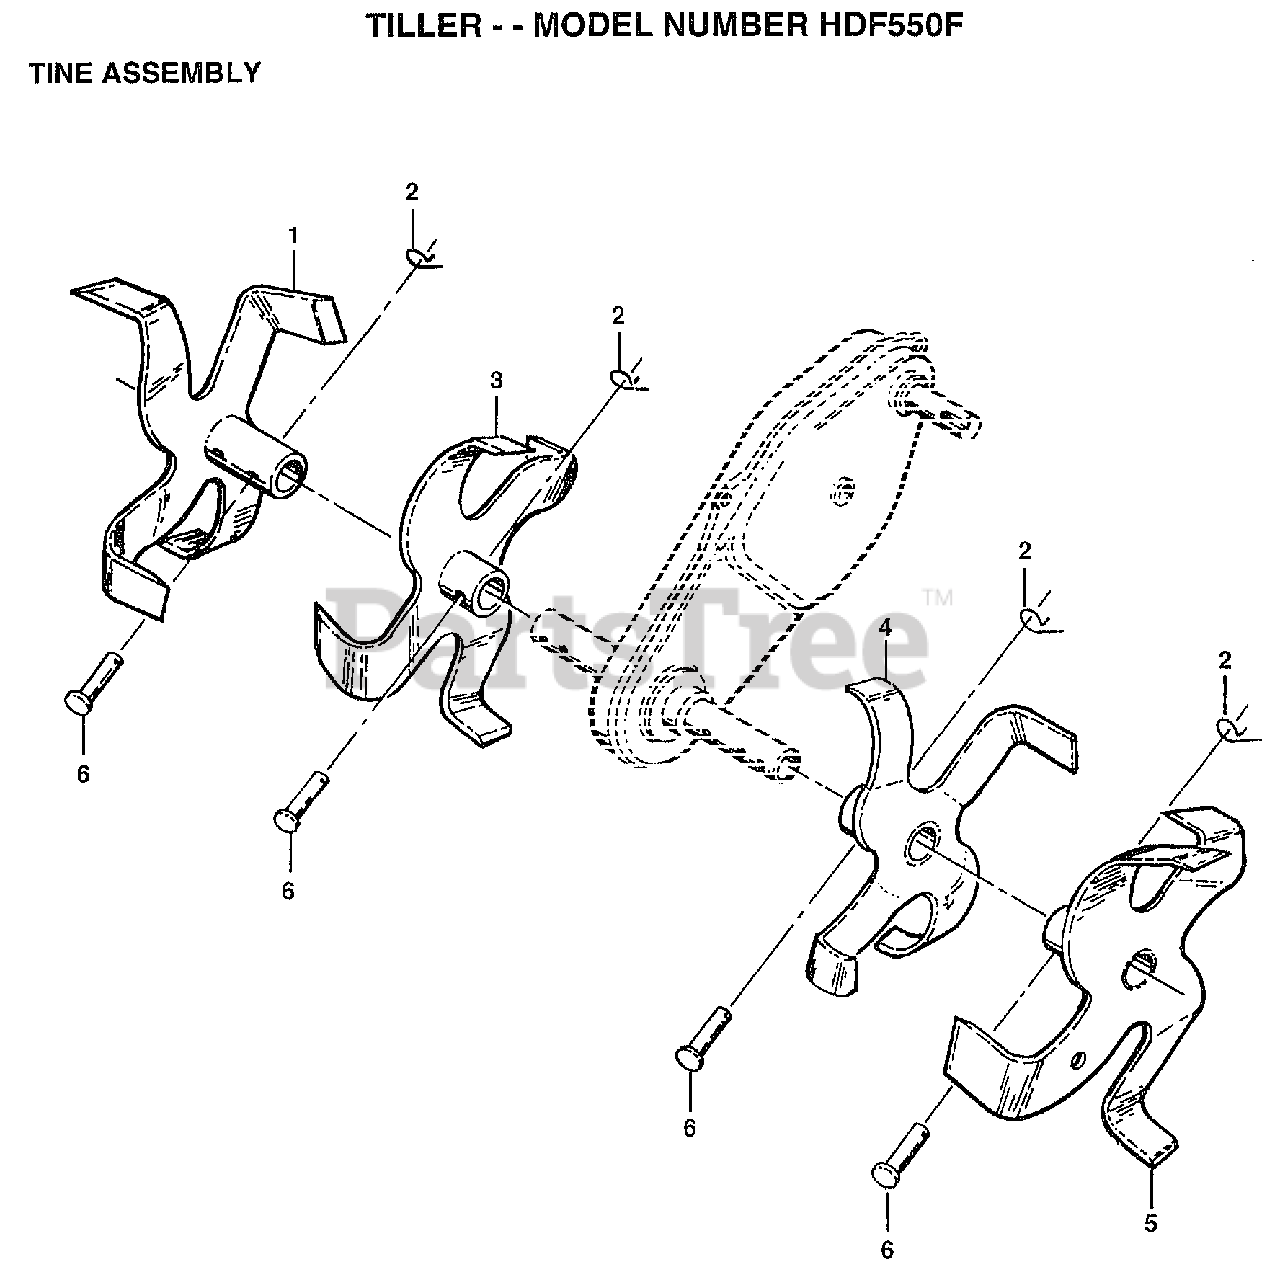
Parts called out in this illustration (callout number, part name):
1	"TINE ASM,OUTER RH"
2	RETAINER.SPRING
3	"TINE ASM.INNER,RH"
4	TINE ASM.INNER LH
5	"TINE ASM,OUTER LH"
6	RIVET.PAN HD.1.75
